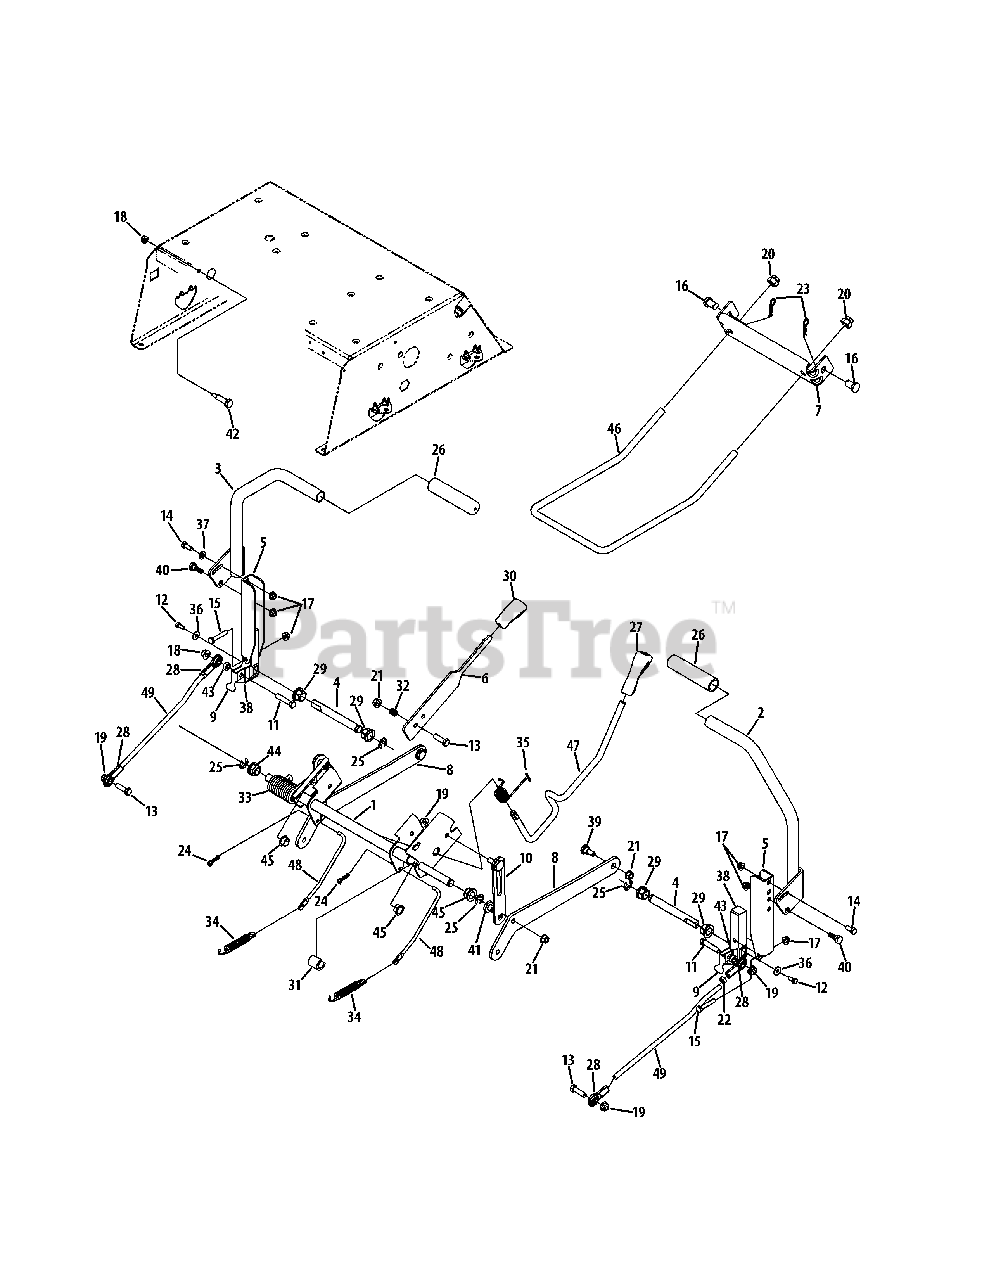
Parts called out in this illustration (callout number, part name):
1	Deck Lift Shaft Assembly
2	RH Lapbar Lever Assembly
3	LH Lapbar Lever Assembly
4	Shaft Control
5	Lapbar Pivot Bracket
6	Brake/Shabs Handle
7	Front Deck Hanger Bracket
8	Deck Lift Arm Plate
9	Actuator Switch Bracket
10	Link Lift Plate
11	Hex Screw, 3/8-16 x 1.75
12	Hex Lock Screw, 1/4-20 x .625
13	Hex Screw, 3/8-16 x 1.25
14	Hex Screw, 5/16-18 x .75
15	Hex Screw, 5/16-18 x 1.75
16	Clevis Pin, .50 x .78
17	Flange Lock Nut, 5/16-18
18	Flange Lock Nut, 1/4-20
19	Flange Lock Nut, 3/8-16
20	Flex Lock Nut, 1/2-13
21	Hex Lock Nut, 3/8-16, Centerlock
22	Jam Nut, 3/8-24
23	Internal Cotter Pin, .080 x 1.5625
24	Bow-Tie Cotter Pin
25	E-Ring, .625
26	Grip, 1.0 x 5.0
27	Handle Grip, 1/2
28	B/Joint Rode End, .375
29	Hex Flange Bearing, .629
30	Selector Handle
31	Spacer, .62 x 1.00
32	Compression Spring, .50 x .50
33	Torsion Spring, 1.19 x 2.78
34	Extension Spring, .59 x 4.00
35	Spring, Torsion RZT
36	Bell Washer, .265 x .75 x .062
37	Flat Washer, .344 x .688 x .065
38	PM Control Hub
39	Shoulder Bolt, 3/8-16 x .496 x .336
40	Shoulder Screw, 5/16-18 x .437 x .268
41	Shoulder Screw, .500 x .434
42	Shoulder Screw, .374 x 1.16
43	Spacer, .380 x .625 x .255
44	Hex Flange Bearing
45	Flange Bearing, .626 x .938 x .344
46	Deck Lift Frong Hanger Rod
47	Deck Lift Handle Rod
48	Brake Rod
49	Lapbar Rod Control
